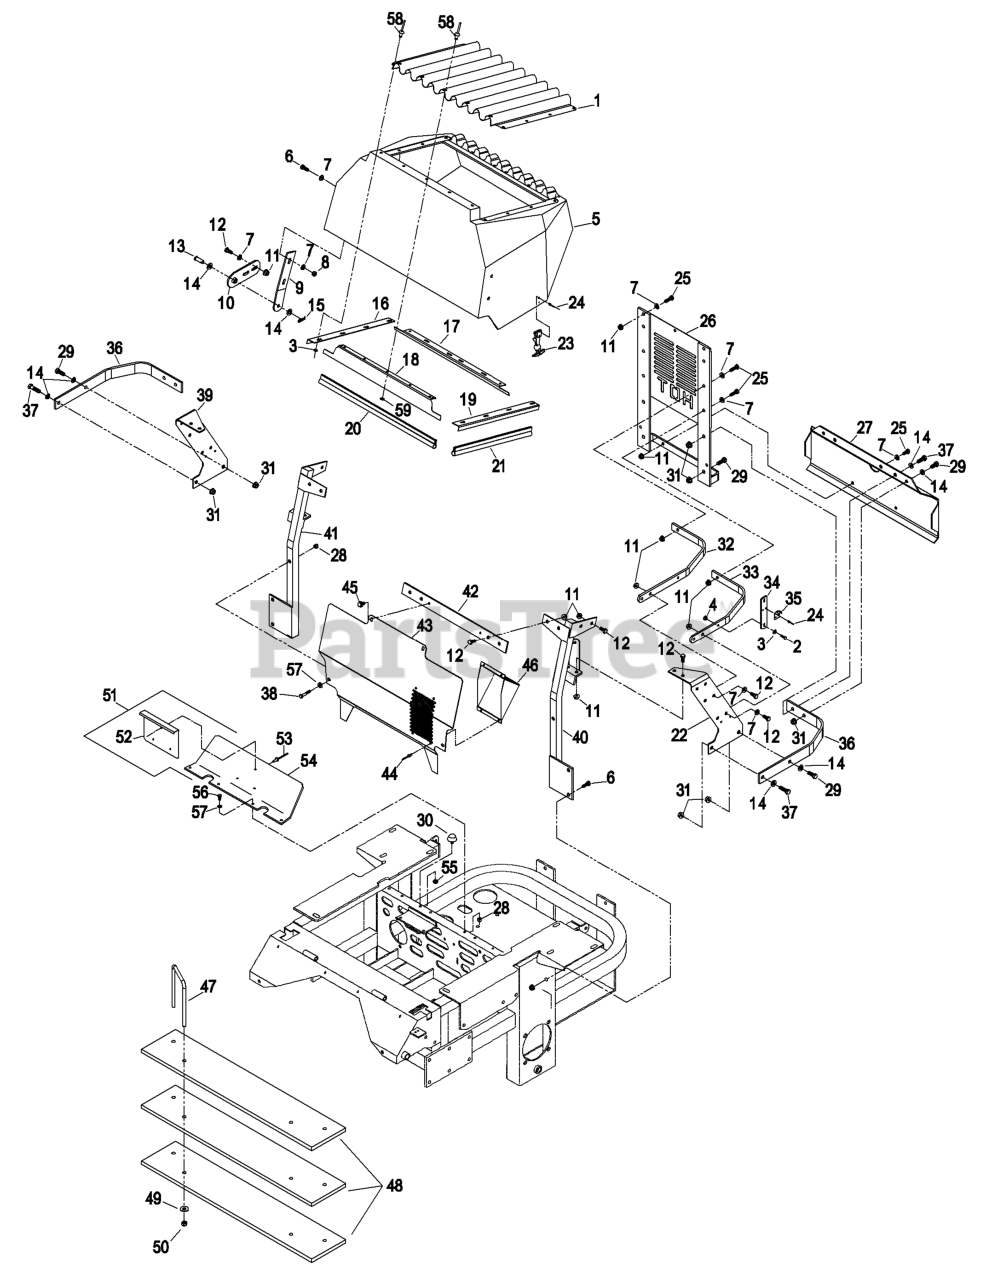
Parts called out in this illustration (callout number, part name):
1	SCREEN-RADIATOR
3	WASHER-FLAT
4	NUT-LOCK, NI
6	SCREW-HH
7	WASHER-PLAIN
8	NUT-LOCK, NI
9	PLATE-HINGE, HOOD
10	SHACKLE-HINGE
12	SCREW-HH
13	PIN-CLEVIS
14	WASHER-FLAT
15	PIN-COTTER
16	ANGLE-RADIATOR, RH
17	ANGLE-RADIATOR, BOTTOM
18	ANGLE-RADIATOR, TOP
19	ANGLE-RADIATOR, LH
20	SEAL-TRIM
21	SEAL-TRIM
22	PLATE-SIDE, LH
23	LATCH-RUBBER
25	SCREW-HH
28	NUT-LOCK, NI
29	SCREW-HH
31	NUT-HHF, WHIZ
34	BAR-HOOK, LATCH
37	SCREW-HH
38	SCREW-HH
39	PLATE-SIDE, RH
40	BRACE-RADIATOR, LH
43	Deflector, Air
44	RIVET-POP
45	SCREW-HWHTF
46	PLENUM-INTAKE, AIR
47	U-BOLT, ZC
49	WASHER-FLAT
50	NUT-LOCK, NI
53	RIVET-POP
54	SHIELD-ENGINE
56	SCREW-HH
57	WASHER-FLAT
59	WASHER-SPRING
